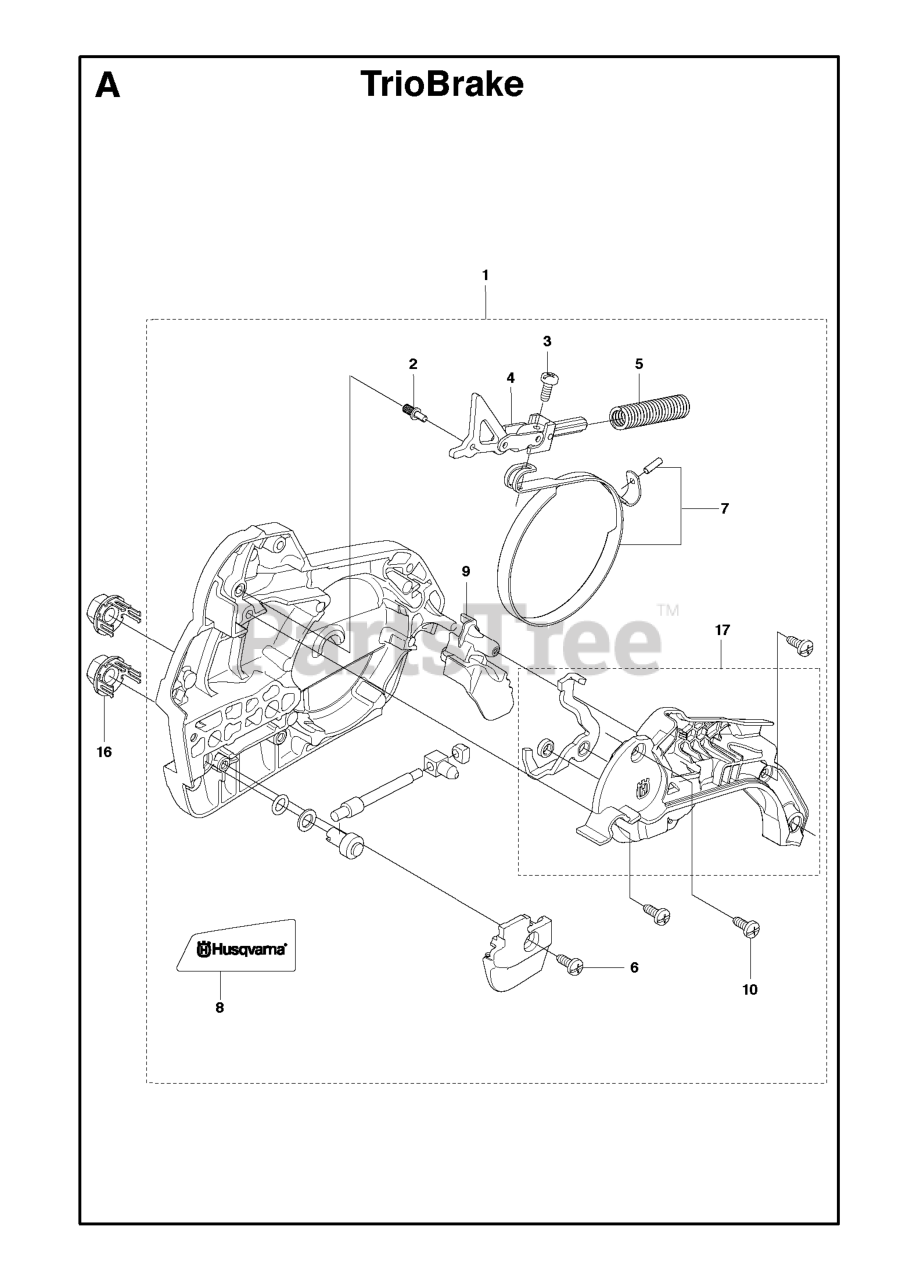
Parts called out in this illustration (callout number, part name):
1	CLUTCH COVER ASSY
1	Clutch Cover Assembly
2	PIN
3	BRAKE BAND ASSY
4	KNEE JOINT ASSY
5	SPRING
6	CHAIN GUIDE
7	BRAKE BAND ASSY
8	LABEL
9	GUARD
10	SCREW
16	NUT RETAINER ASSY
17	COVER LID ASSY
